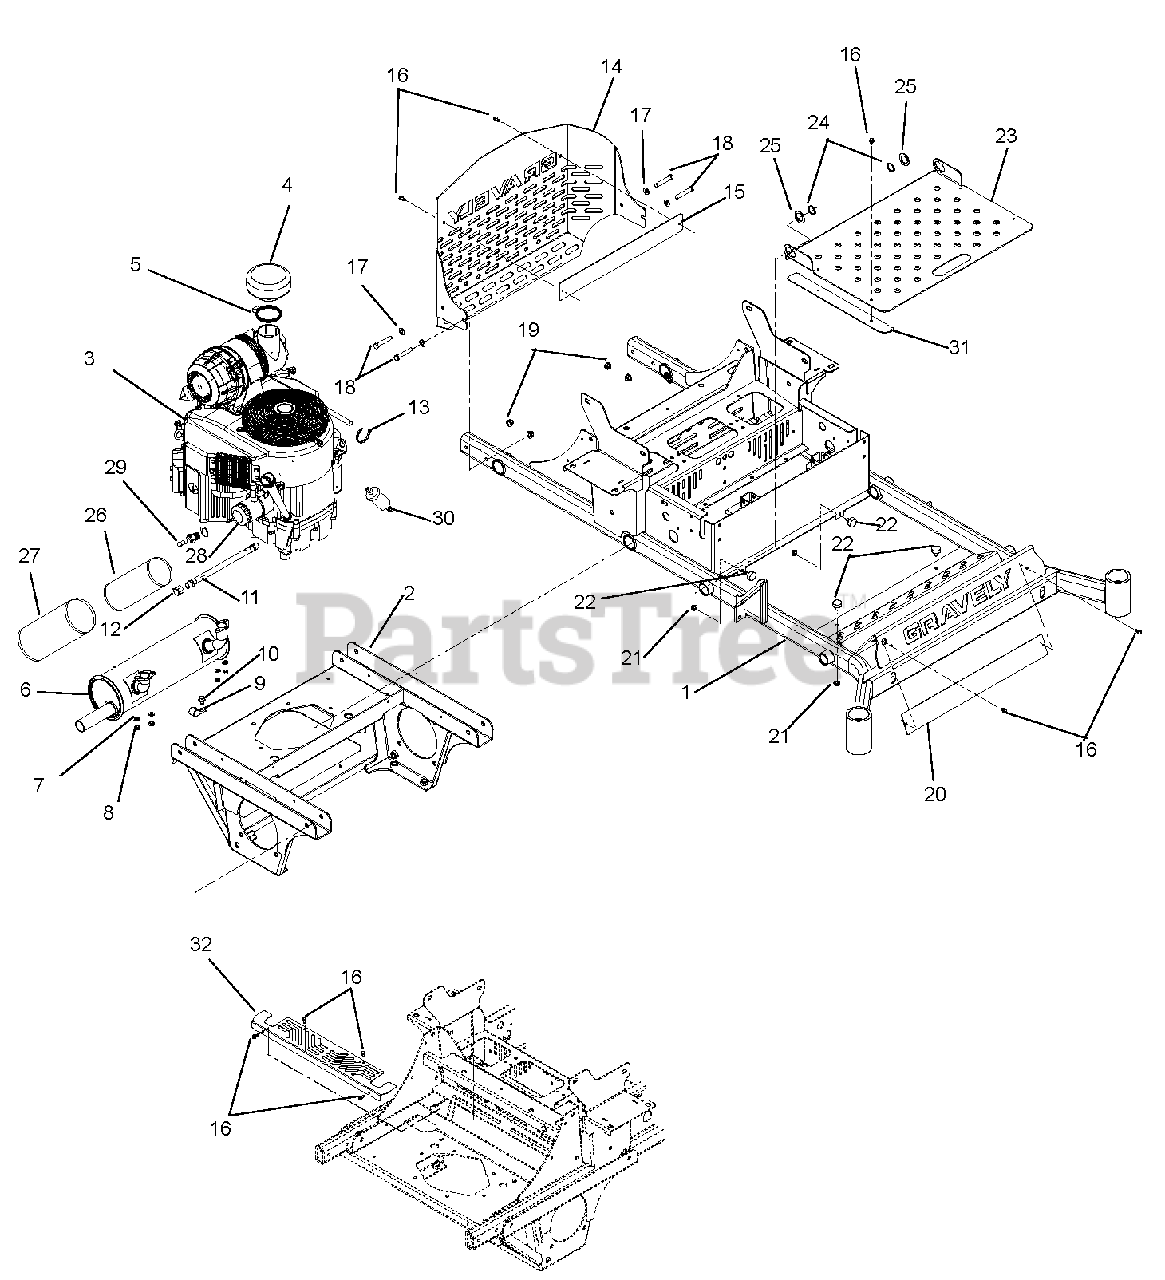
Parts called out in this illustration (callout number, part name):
1	Weldment, 52" – 66" 200PT Main Frame
2	Weldment, 200PT Axle/Engine Frame
3	Engine, Kawasaki FX730
4	Rain Cap, Air Cleaner
5	Clamp, Hose 2.75 DIA Worm
6	Muffler, Kawasaki Fixed 24/26HP
7	Washer, Lock .31 x .078 REG YWZC
8	Nut, Locking Top M8-1.25 YWZC
10	Screw, Tap .38-16 x .50 Hex Washer Head TR YWZ
11	Hose, Hydraulic .38-14-0K M6N0-M6N0
12	Pipe Cap 3/8 NPT Female
13	Cable Tie LG 5-1/2
14	Weldment, Bumper, Pro-Turn 200
15	Plate, Bumper, Pro-Turn 200
16	Screw, Tap .25-20 x .50 Hex Washer Head TR YWZ
17	Washer, Flat Steel .406 x .812 x .065 YWZ
18	Bolt, Hex .38-16 x 2.25 GR5 YWZC
19	Nut, Locking Nylon Flange .38-16 YWZC
20	Plate, Bumper Name Backer
21	Nut, Spin Lock Flange .312-18
22	Bumper, Rubber
23	Inspection Panel
24	Ring, Retaining, External 1.00 x .078
25	Washer, Flat Steel 1.010 x 1.505 x .062
26	Element, Inner Safety
27	Element, Outer Primary
28	Oil Filter
29	Spark Plug
30	Fuel Filter
31	Guard, Foot Plate, Finger
32	Guard, CE Rear Access
